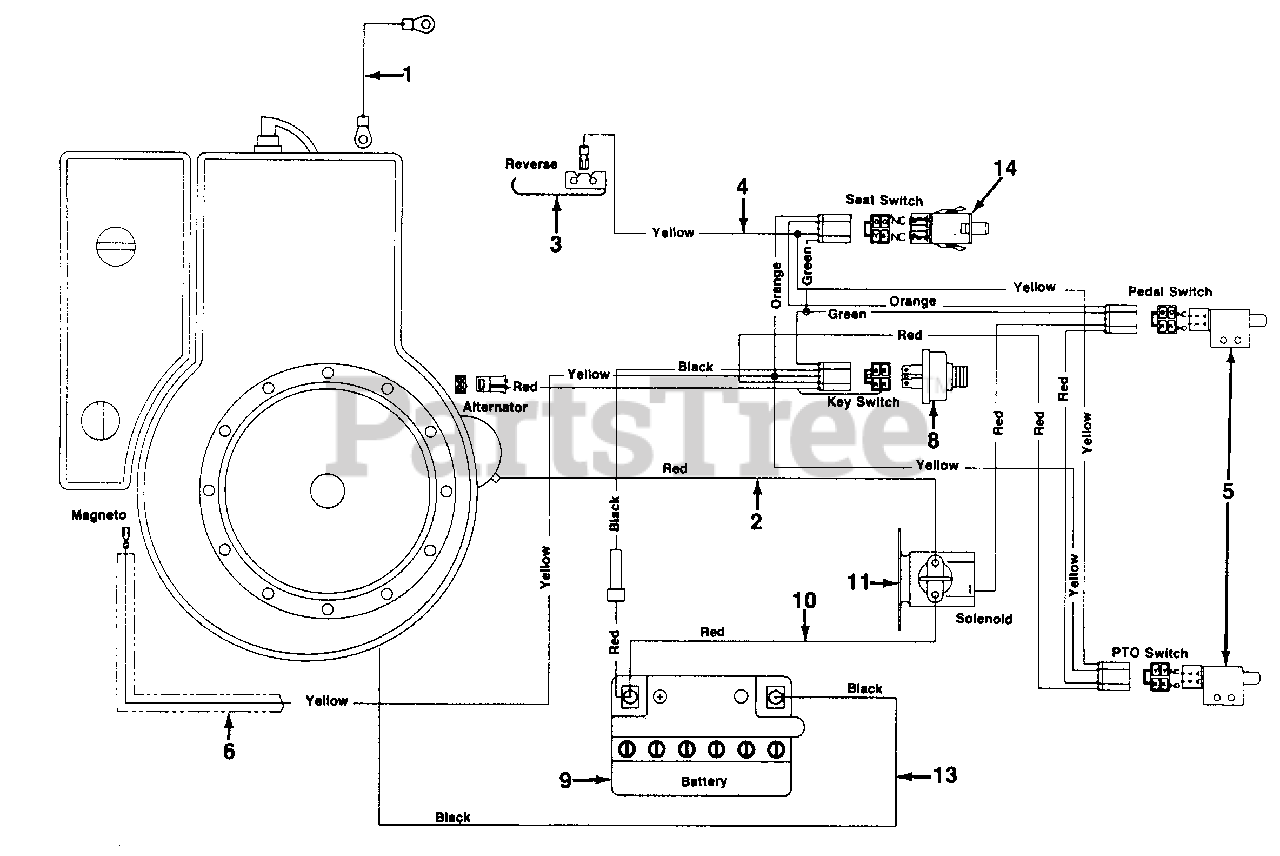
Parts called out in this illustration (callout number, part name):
1	Elec. Wire 8 Ga. x 9.0" Lg.
2	Elec. Wire
3	Spring Switch-Reverse
4	Wire Harness
5	Safety Switch
6	Convoluted Tubing 29" Lg.
8	Ignition Switch
9	Battery 12V
10	Elec. Wire Red w/Boot
11	Solenoid
13	Elec. Wire 8 Ga. x 9.0" Lg.
14	Seat Switch
